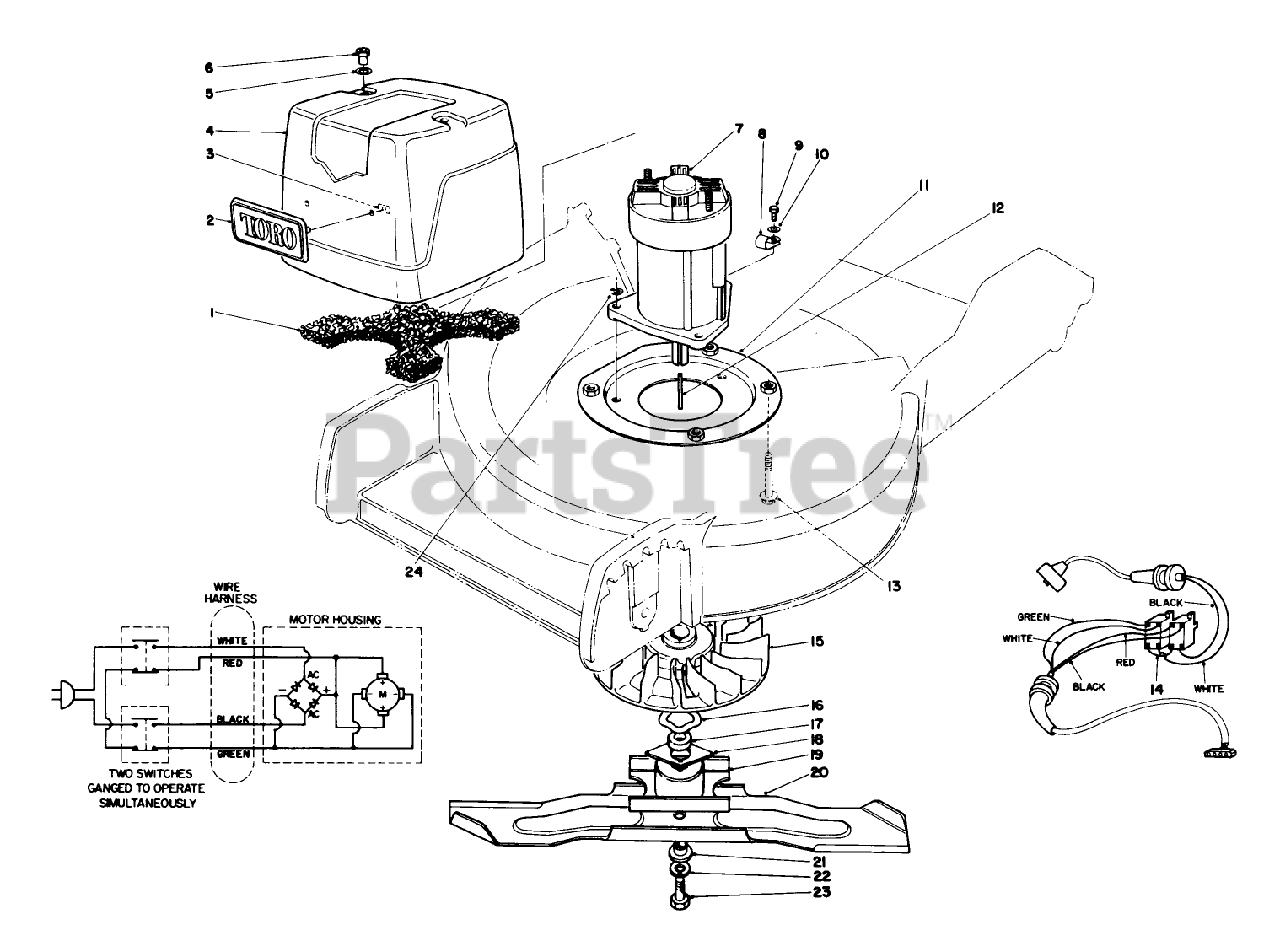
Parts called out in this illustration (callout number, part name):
8	CLAMP
9	SCREW-HH
10	WASHER-FLAT
12	KEY-SQUARE
13	SCREW-HHF
19	BLADE RETAINER WA
23	SCREW-HH
24	WASHER-LOCK/EXT
